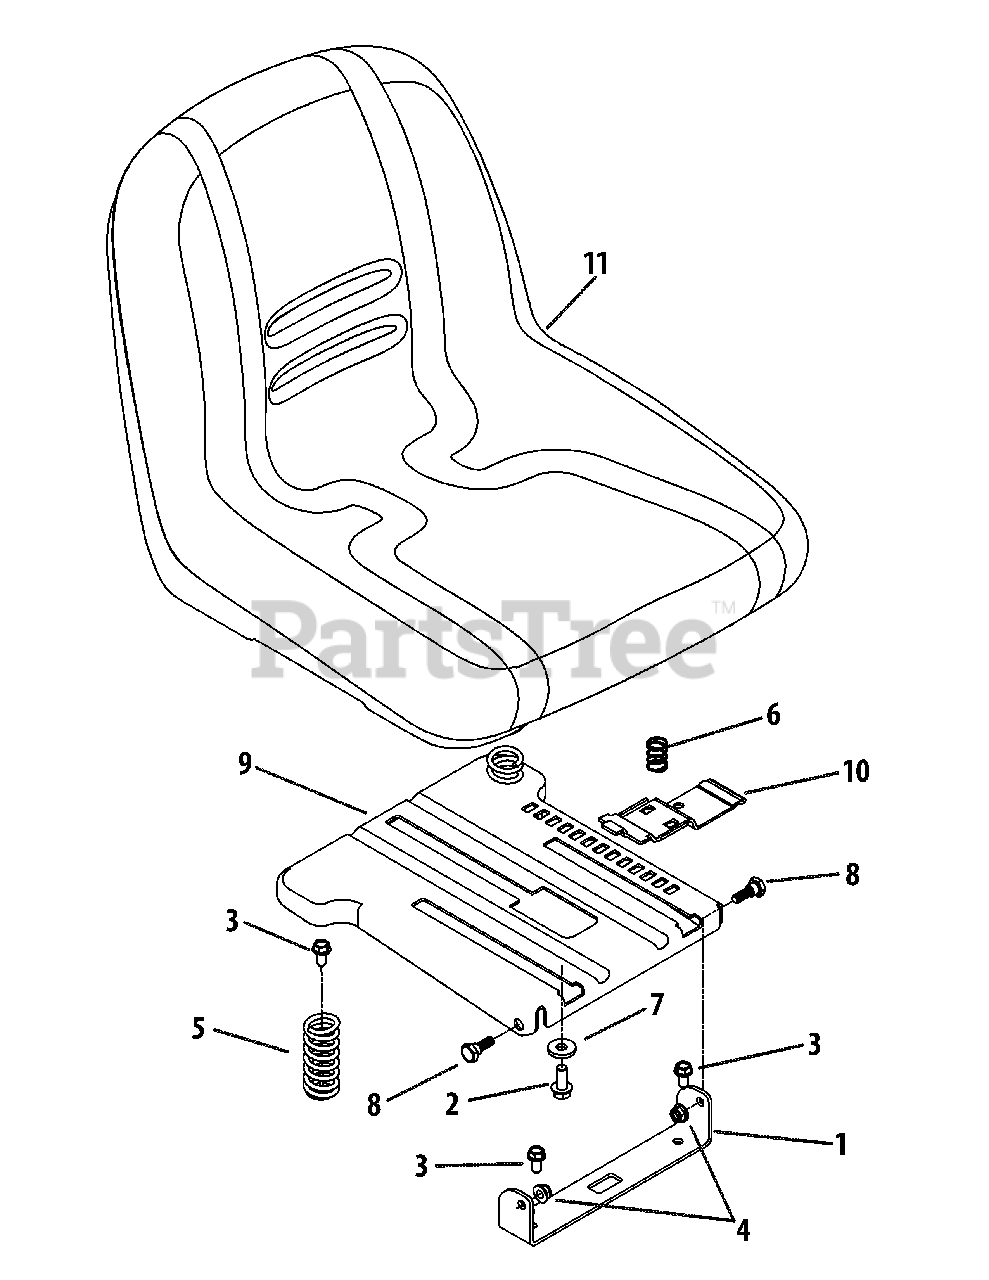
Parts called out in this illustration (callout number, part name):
2	Hex Flange Bolt, 3/8-16 x .875
3	Hex Washer Screw, 5/16-18 x .750
4	Flange Lock Nut, 5/16-18
5	Compression Spring
6	Compression Spring
7	Flat Washer, .385 x 1.0 x .135
8	Shoulder Screw, 5/16-18 x .437 x .268
9	Seat Mount Bracket
10	Seat Adjustment Lever
11	High Back Seat
